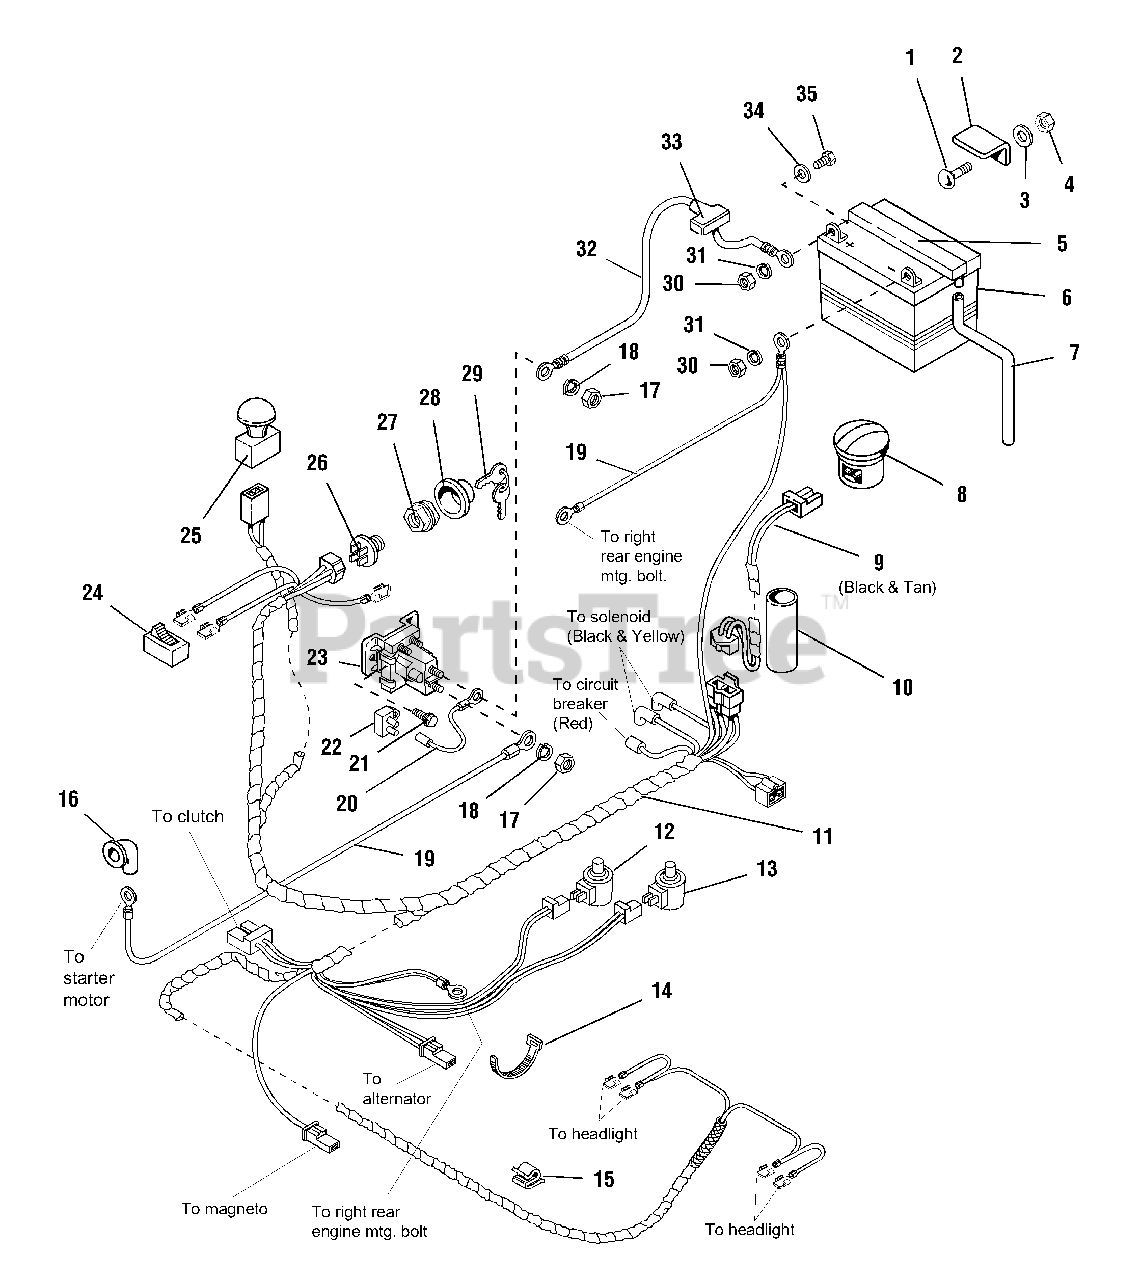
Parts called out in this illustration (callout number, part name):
1	CARRIAGE BOLT, 5/16-18 x 3/48
2	CLAMP, Battery
3	WASHER, Plain, 5/16
4	NUT, Hex, Nylon Lock, 5/16-18
5	CAP, Vent, Battery
7	HOSE, Drain
8	SWITCH, Seat
9	WIRE ASSY., Seat Switch
10	TUBE, Shrink
11	WIRING HARNESS
12	SWITCH, Pedal, N.O., Black
13	SWITCH, Pedal, N.C., Gray
15	CLIP, Wire
16	COVER, Terminal
17	NUT, Hex, 5/16-24 NF
18	LOCKWASHER, 5/16
19	CABLE
21	SCREW, Taptite, 1/4-20 x 5/8
22	CIRCUIT BREAKER
23	SOLENOID
24	SWITCH, Headlights
25	SWITCH, PTO
26	SWITCH, Ignition, 6-Pole
27	NUT, Hex, Flange, 5/8-8
28	COVER, Ignition
29	KEY, Ignition
30	NUT, Hex, 1/4-20
31	LOCKWASHER, 1/4
32	CABLE, Battery, Positive
33	BOOT, Insulator
34	WASHER, 1/4
35	CAPSCREW, Hex Hd., 1/4-20 x 3/4
